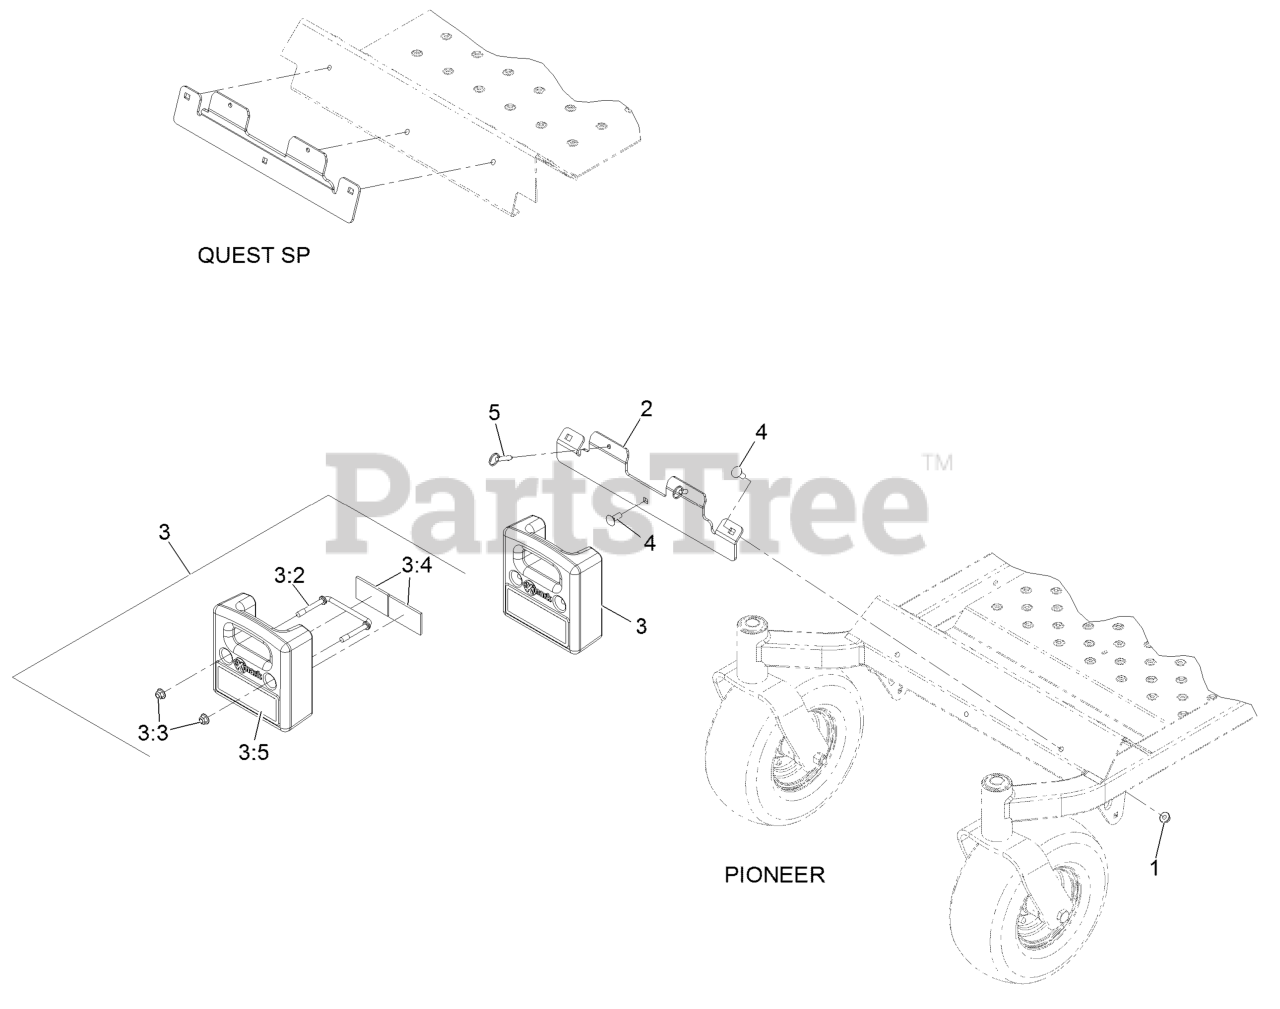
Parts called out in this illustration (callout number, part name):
1	NUT-HF, NI
2	BRACKET-WEIGHT MOUNT
3	WEIGHT ASM
3:2	WIREFORM-WEIGHT
3:3	NUT-HF, NI
3:4	CUSHION-RUBBER
3:5	DECAL-WARNING WEIGHT
4	BOLT-CARR
5	PIN-BALL, DETENT
